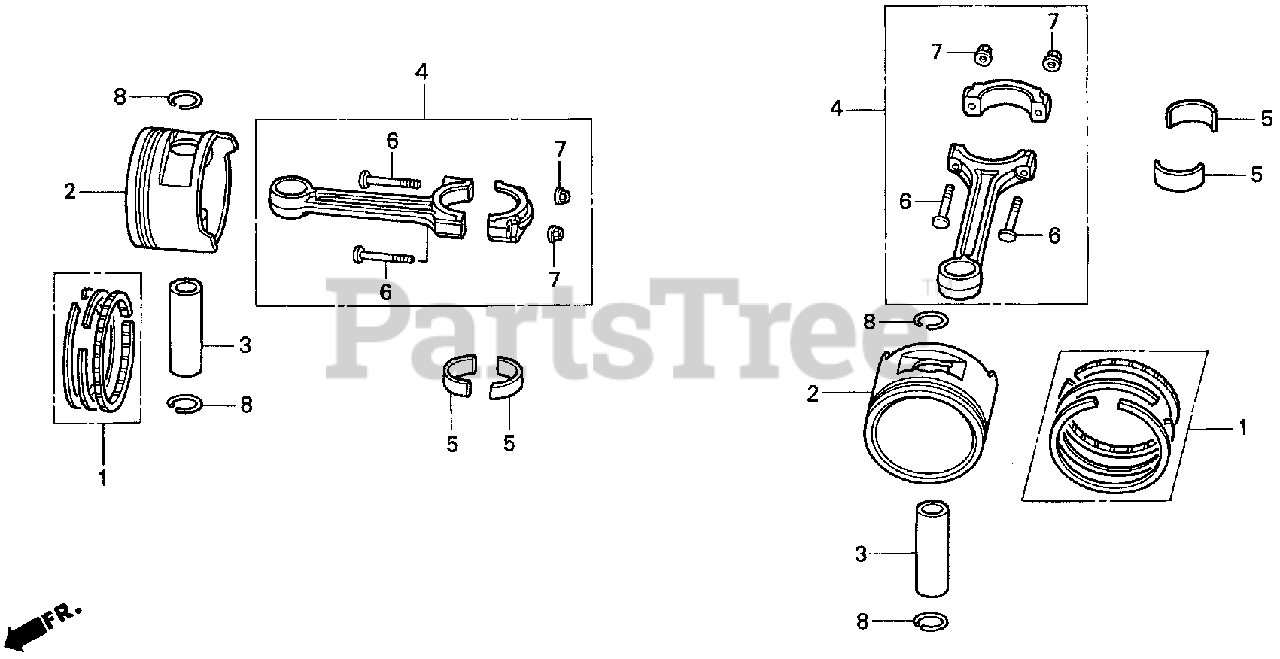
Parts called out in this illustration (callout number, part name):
1	RING SET, PISTON (STD)
1	RING SET, PISTON (OS 0.25)
1	RING SET, PISTON (OS 0.50)
1	RING SET, PISTON (0.75)
2	PISTON
2	PISTON (OS 0.25)
2	PISTON (OS 0.50)
2	PISTON (0.75)
3	PIN, PISTON
4	ROD SET, CONNECTING
5	BEARING A, CONNECTING ROD (BLUE)
5	BEARING B, CONNECTING ROD (BLACK)
5	BEARING C, CONNECTING ROD (BROWN)
5	BEARING D, CONNECTING ROD (GREEN)
5	BEARING E, CONNECTING ROD (YELLOW)
5	BEARING F, CONNECTING ROD (PINK)
5	BEARING G, CONNECTING ROD (RED)
6	BOLT, CONNECTING ROD
7	NUT, CONNECTING ROD
8	CLIP, PISTON PIN (18MM)
